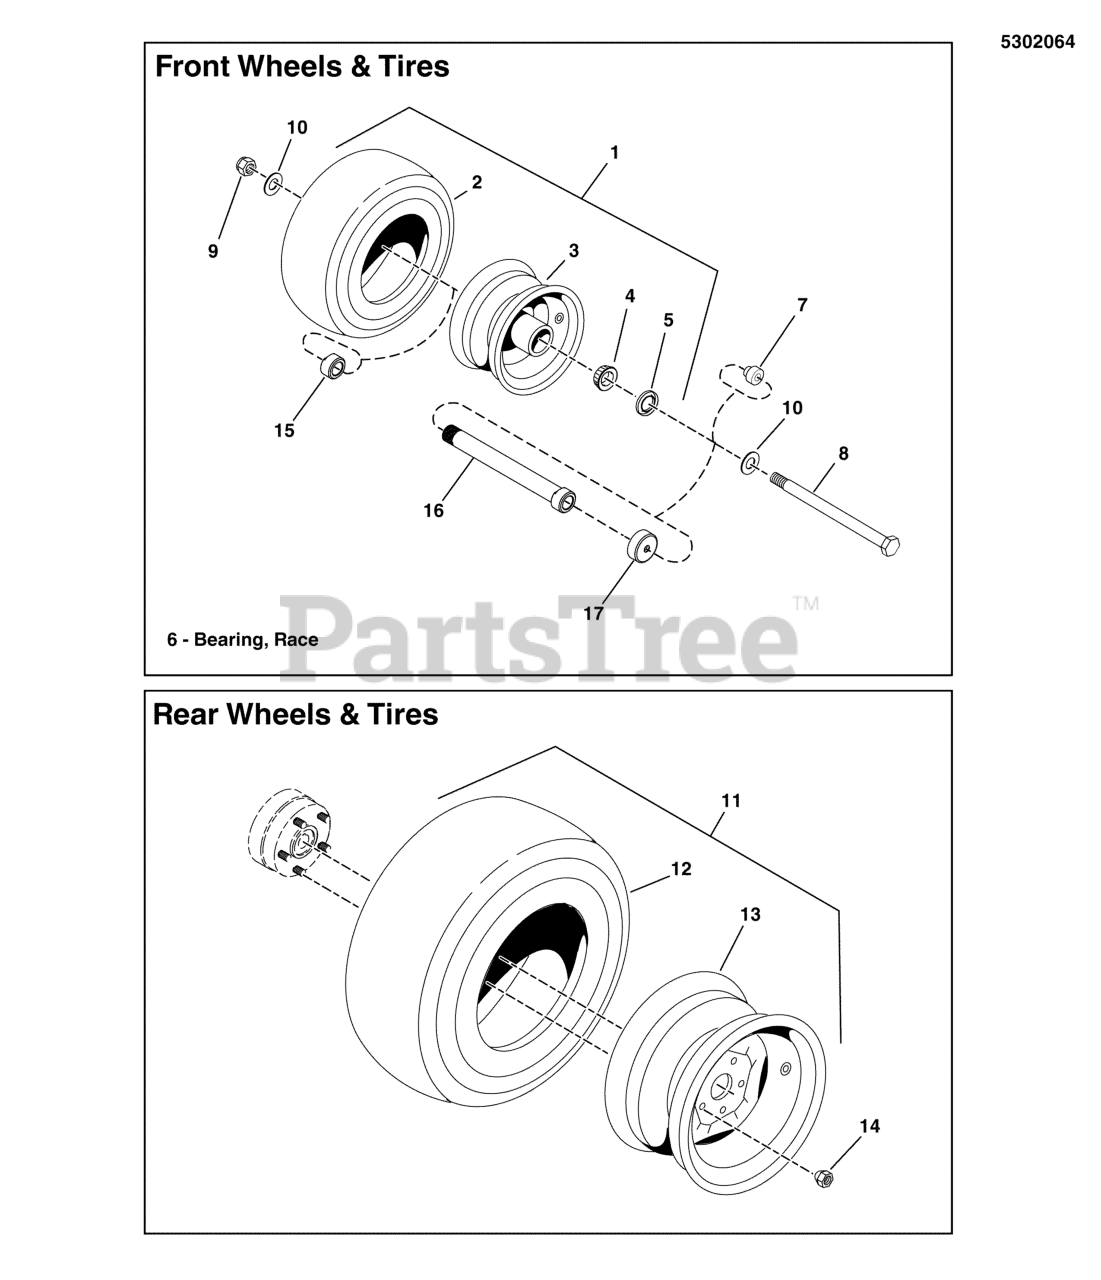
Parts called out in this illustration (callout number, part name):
1	TIRE, CASTER, 13 X 5.00-6
3	WHEEL ASSY, 13 X 5 X 6, SILVER
4	BEARING, Tapered Roller
5	SEAL, GREASE
6	BEARING, RACE
7	ADAPTER, CASTER AXLE, CZ
8	BOLT, 1/2-13 X 8 GD5 YZ
9	NUT, Hex Flange, Nylock, 1/2-13
10	WASHER, 1/2 SAE
11	TIRE ASSM, 22 X 11.00-10
11	TIRE ASSM, 22 X 10.00-10
12	TIRE, 22 X 11.00-10, 4 PLY
12	TIRE, 22 X 10 X 10
13	RIM-10X7-5-4.5 SOLID
14	NUT, 1/2-20, FOR WHEEL BOLT SILVER
15	NUT, BEARING ADJUSTER, AXLE
16	BEARING ADJUSTER, SPACER, 6.062 LG
17	DEBRIS COVER, CASTER WHEELS
